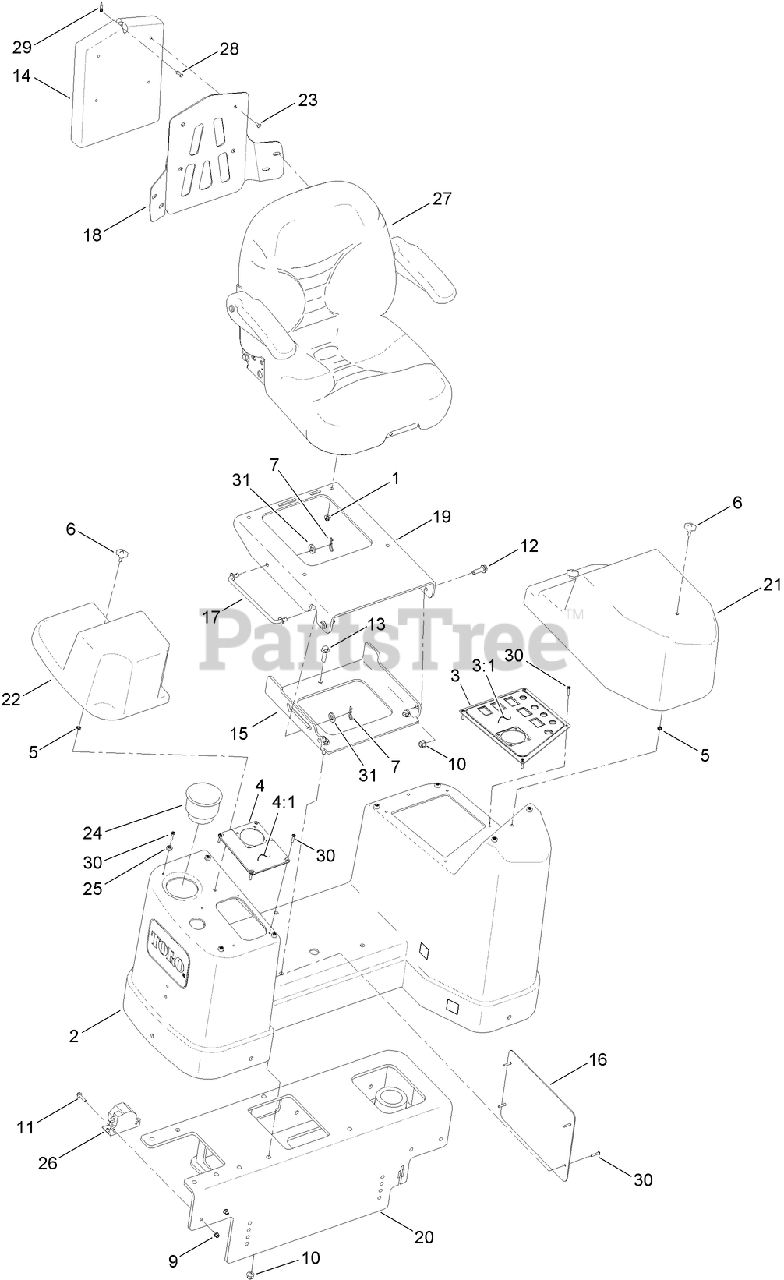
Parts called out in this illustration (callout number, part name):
1	NUT-HF, NI
2	OPERATOR CONSOLE ASM
3	SWITCH PLATE ASM
3:1	DECAL-JOYSTICK, LEFT
4	JOYSTICK MOUNTING PLATE ASM
4:1	DECAL-JOYSTICK, RIGHT
5	RING-RETAINING
7	PIN-HAIR
9	NUT-FLANGE, NI
10	NUT-LOCK, NI
11	SCREW-HHF
12	SCREW-HHF
13	SCREW-HHF
14	HOLDER-MANUAL, OPERATOR
15	PLATE-SEAT MOUNT, BOTTOM
16	PLATE-SEAT, INSIDE PANEL
17	ROD-PROP, SEAT
18	PLATE-MOUNT, MANUAL
19	PLATE-SEAT MOUNT, TOP
20	CONSOLE-OPERATORS
21	COVER-CONSOLE, LH
22	COVER-CONSOLE, RH
23	RIVET-BLIND
24	CUP-HOLDER
25	GROMMET-RUBBER
26	ALARM-BACKUP
27	OPERATOR SEAT ASM (STATIC)
28	POST-MANUAL
29	LANYARD
30	SCREW-PPH
31	WASHER-FLAT
